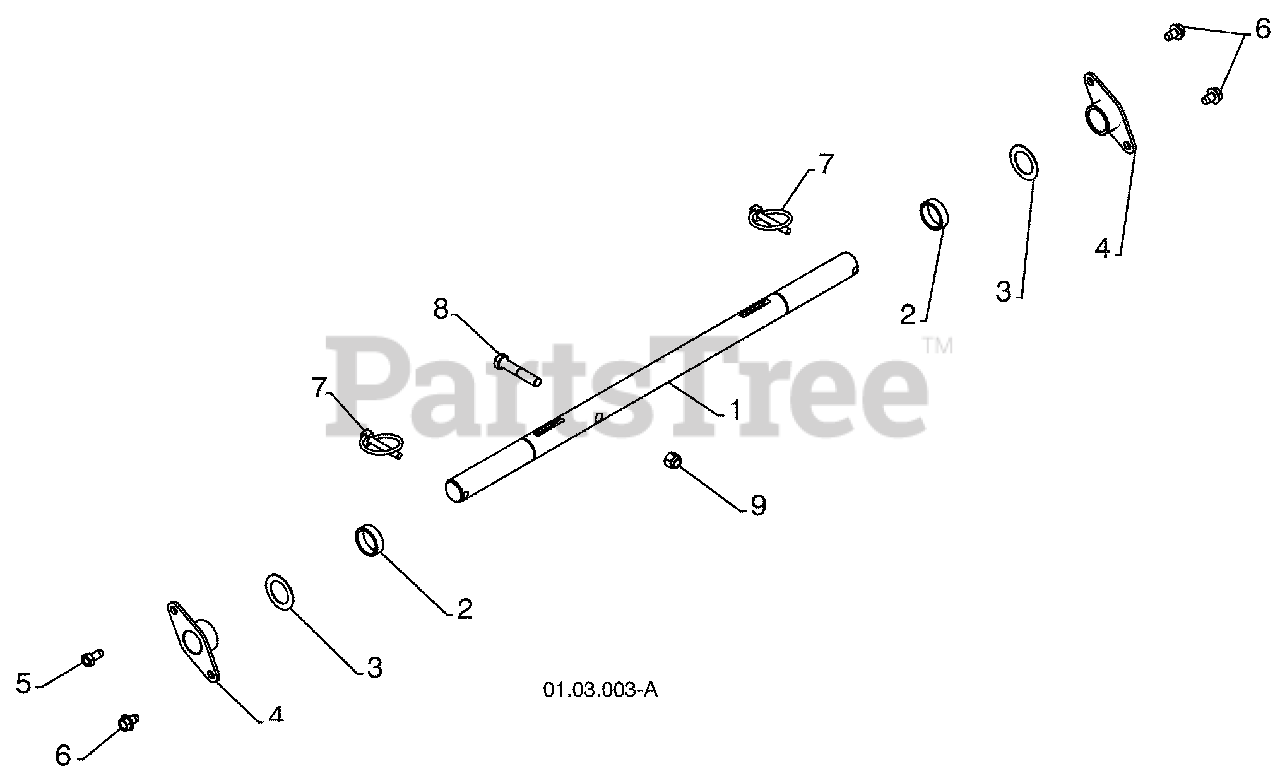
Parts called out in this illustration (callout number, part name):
1	AXLE SHAFT
3	THRUST WASHER
5	SCREW 5/16--18 X .625
6	BOLT 5/16--18 X .500
8	SCREW 3/8--16 X 2.00
9	NUT 3/8--16
